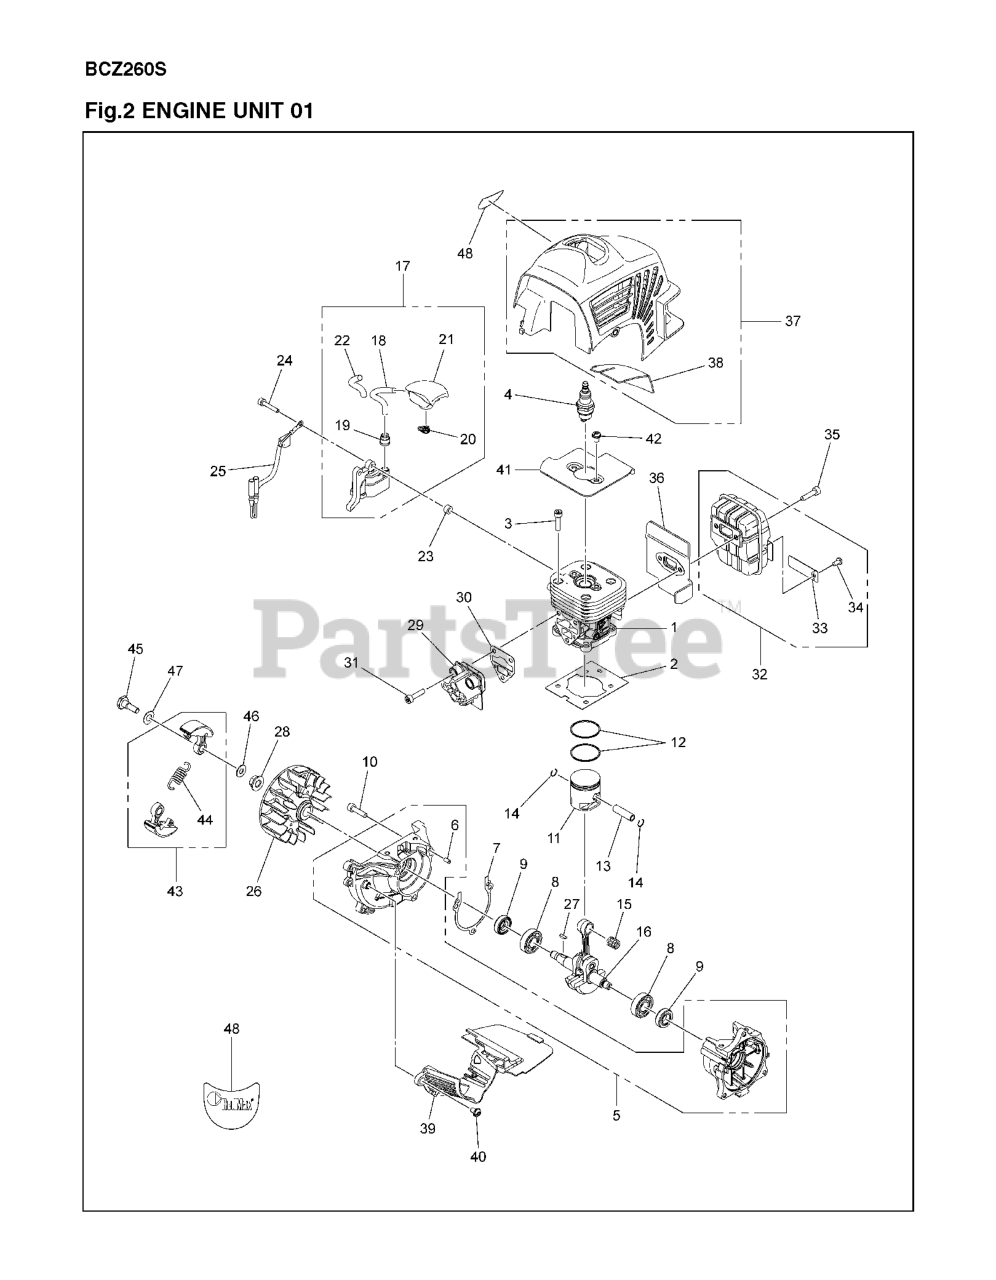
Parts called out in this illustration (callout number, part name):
1	CYLINDER COMP
2	GASKET BASE
4	SPARK PLUG, BPMR8Y
5	CRANKCASE ASSY
7	GASKET CASE
13	PIN
16	CRANKSHAFT COMP
17	IGNITION MODULE
18	IGNITION CABLE
19	HUB CAP 848F6L71E0
21	SPARK PLUG CAP
22	TUBE (RPLS 263072210)
23	SPACER
24	BOLT M4 X 25
25	SHORT CIRCUIT CABLE
26	FLYWHEEL
27	KEY
28	NUT
29	INSULATOR
32	MUFFLER ASSY
33	SPARK ARRESTER
34	SCREW CRPANT TYPE F ST4.2X9.5
36	GASKET MUFFLER
37	CYLINDER COVER COMP
38	SHEET HEAT INSULATION
39	PLATE MUFFLER
41	PLATE CYLINDER
43	CLUTCH ASSY
44	CLUTCH SPRING
48	DECAL BRAND
